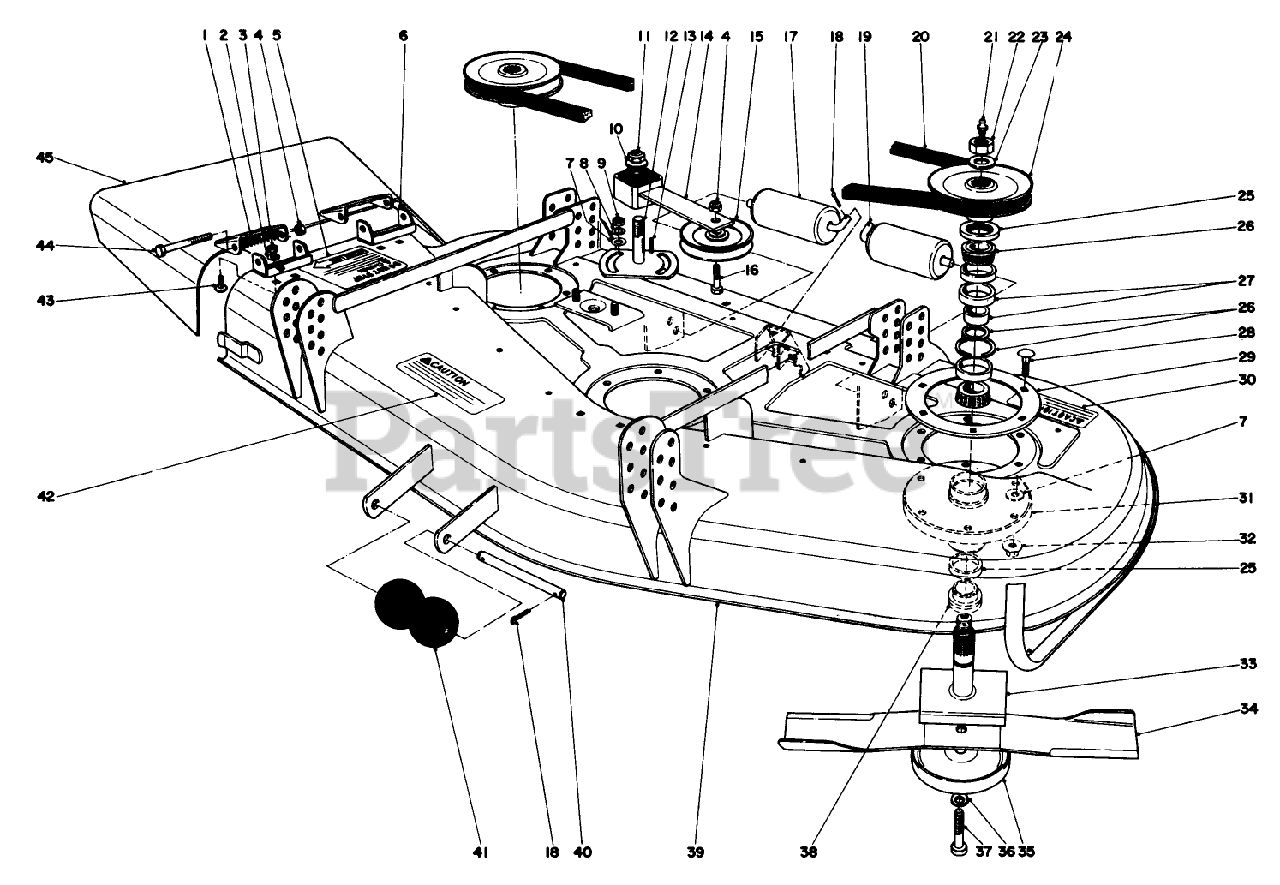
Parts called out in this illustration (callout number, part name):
1	SPRING
2	WASHER-LOCK
3	NUT-HEX
4	NUT-HEX
5	Decal-Caution
6	Bracket-Pivot
7	WASHER-FLAT
8	WASHER-LOCK
9	NUT-JAM
10	WASHER-FLAT
11	NUT-LOCK, NI
12	PLATE-IDLER
13	KEY-SQUARE
14	IDLER ARM ASM
15	Idler Pulley
16	SCREW-HH
17	ROLLER-DECK
18	PIN-COTTER
19	SHAFT-ROLLER, REAR
20	V-BELT
21	FITTING-GREASE
22	NUT-HEX
23	WASHER
24	PULLEY AND HUB ASM
25	SEAL-OIL
26	BEARING ASM
27	SPACER-SET, MATCHED
28	SCREW-CARR
29	SUPPORT-DECK, RING
30	DECAL-CAUTION, BLADE
31	Housing-Spindle
32	NUT-HF
33	SHAFT
34	Blade
35	Cup-Scalp
36	WASHER-LOCK
37	Capscrew
38	SPACER
39	GM 52 DECK WA RO
40	SHAFT-ROLLER
41	ROLLER
42	Decal-Caution
43	SCREW-CARR
44	SCREW-HH
45	Deflector
